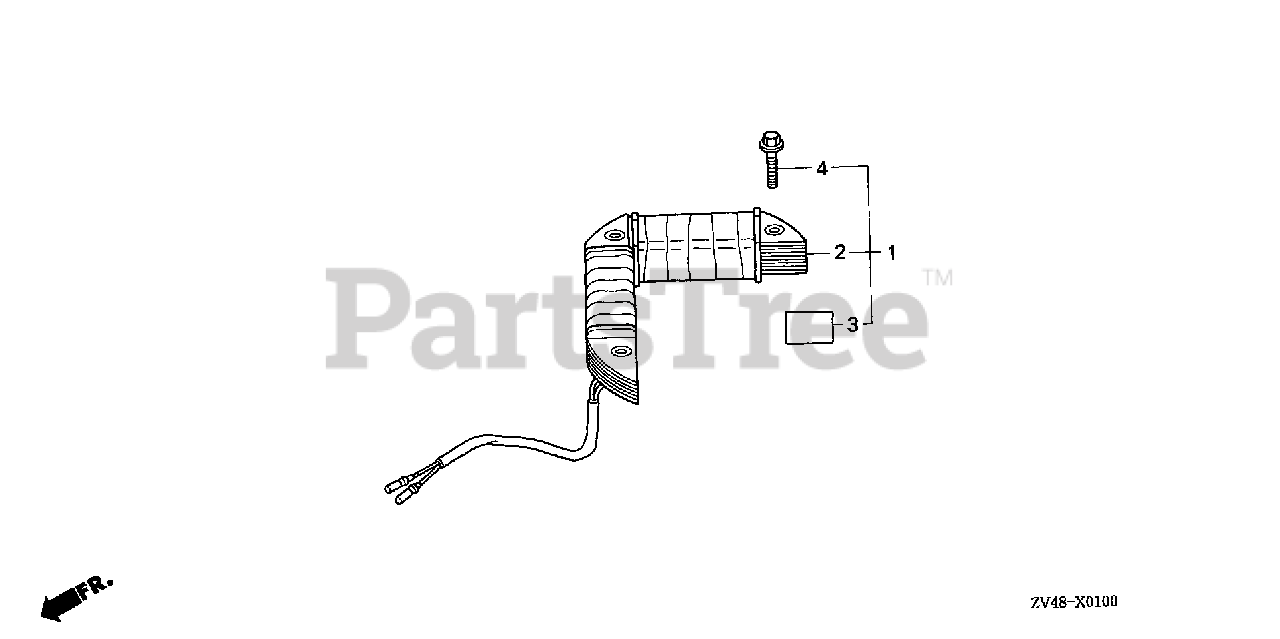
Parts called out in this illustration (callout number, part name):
1	COIL KIT, CHARGE (10A)
2	COIL ASSY., CHARGE (12V-10A)
3	MARK, RECEPTACLE (10A)
4	BOLT, FLANGE (6X32)
